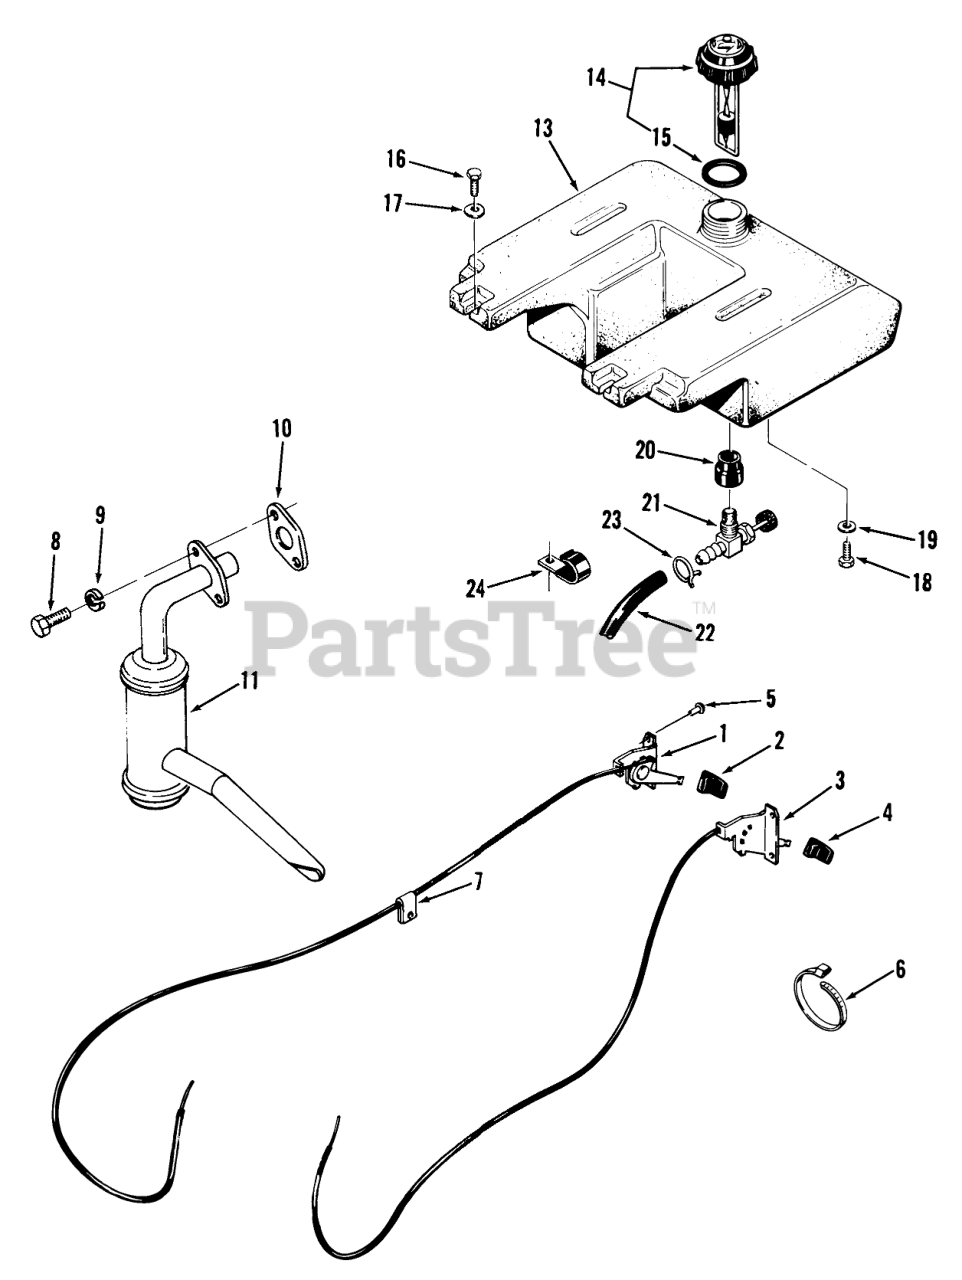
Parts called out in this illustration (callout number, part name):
1	THROTTLE CONTROL
2	KNOB-THROTTLE
3	CONTROL-CHOKE
4	KNOB-CHOKE
5	Pip Rivet
6	PLASTIC TIE
7	THROTTLE CONTROL CLP
8	Bolt
9	Lockwasher
10	Gasket Exhaust
11	Muffler
13	TANK-FUEL
14	ASSY-GAUGE CAP
15	GASKET-GAS CAP
16	Bolt
17	Washer
18	Bolt
19	Lockwasher
20	BUSHING
21	VALVE-FUEL
22	Fuel Line
23	Clamp
24	CLIP
